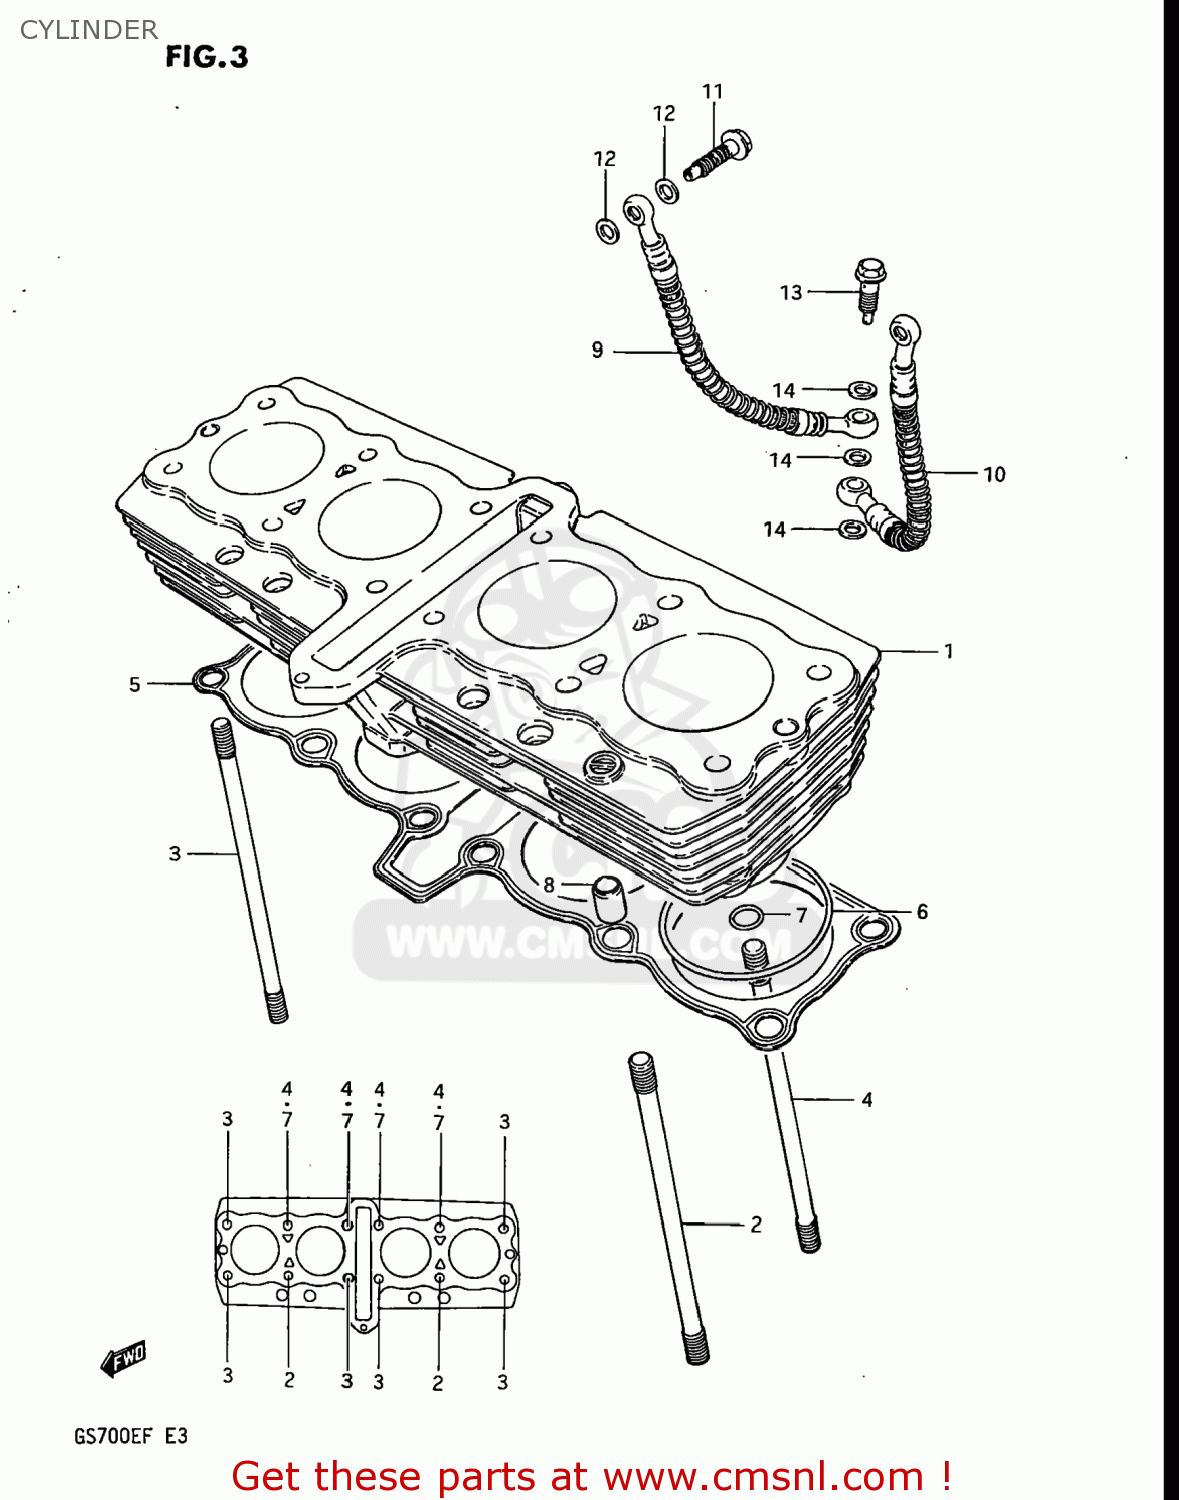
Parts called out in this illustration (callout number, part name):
1	CYLINDER
2	BOLT,STUD
3	STUD
4	STUD
5	GASKET,CYLINDER (NAS)
6	O RING(D:2,ID:70)
7	O RING(D:2.4,ID:11)
8	PIN
9	HOSE,OIL
10	HOSE,OIL
11	BOLT UNION
12	GASKET 8.2X14X1 (NAS)
13	BOLT,OIL PIPE
14	WASHER(10X15X1.5)
